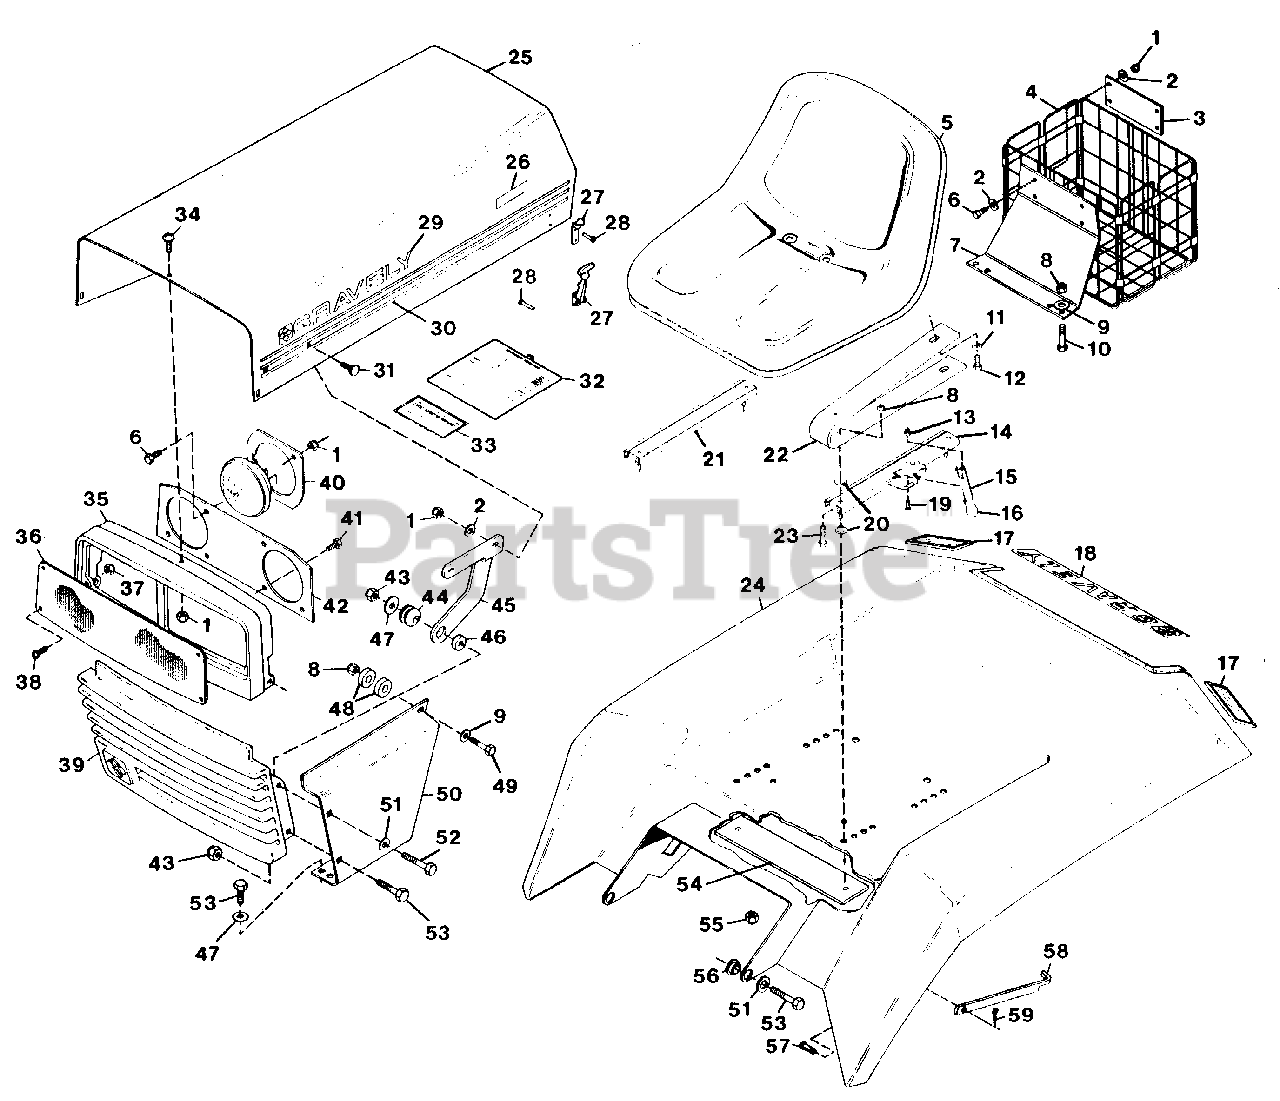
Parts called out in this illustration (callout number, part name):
1	NUT, LOCK 1/4-20
2	WASHER, FLAT .281X.625X.065
3	STRAP, BASKET
4	BASKET
5	SEAT, HIGH BACK
6	BOLT, HEX 1/4-20X1.00
7	BRACKET, BASKET
8	NUT, LOCK 5/16-18
9	WASHER, FLAT .344X.688X.065
10	BOLT, HEX 5/16-18X2.00
11	WASHER, LOCK 5/16 REG.
12	BOLT, HEX 5/16-18X.75
13	NUT, LOCK 10-24
14	ADJUSTER, SEAT W/LATCH
15	HANDLE, SEAT SLIDE
16	TIP, LEVER
17	REFLECTOR, RED SAFETY
18	DECAL, GRAVELY LOGO
19	SCREW, MACHINE 10-24X.625 PHD
20	BUSH., FLG. .375X1.16X.320 STL.
21	ADJUSTER, SEAT
22	SPRING, SEAT
23	BOLT, HEX 5/16-18X1.25
24	WELDMENT, SEAT PAN NOTCHED
25	HOOD, SILK SCREEN
26	DECAL, MODEL 24-G
27	LATCH, FLEXIBLE
28	RIVET, DOME HEAD
29	DECAL, GRAVELY LOGO
30	DECAL, SIDE STRIPE L.H. AND R.H.
31	BOLT, 1/4-20X.75 RD HD SQ NK
32	DECAL, MAINTENANCE
33	DECAL, ELECTRICAL SYSTEM WARNING
34	SCREW, MACHINE 1/4-20 PHD
35	BEZEL, HEADLIGHT
36	PANEL, HEADLIGHT LENSE
37	NUT, LOCK 10-24
38	SCREW, MACHINE 10-24X.75 PHD
39	CASTING, GRILLE
40	RING, HEADLIGHT RETAINER
41	SCREW, 1/4-20X.50 SELF-TAPPING
42	PANEL, HEADLIGHT REFLECTOR
43	NUT, LOCK 3/8-16
44	GROMMET
45	HINGE, HOOD L.H.
45	HINGE, HOOD R.H.
46	SPACER
47	WASHER, FLAT .438X1.000X.083
48	BUSH., ST. .391X1.00X.250 STL.
49	BOLT, HEX 5/16-18X1.75
50	PANEL, SIDE L.H.
50	PANEL, SIDE R.H.
51	WASHER, FLAT .406X.812X.065
52	BOLT, HEX 3/8-16X2.00
53	BOLT, HEX 3/8-16X1.00
54	BRACKET, SEAT
55	NUT, LOCK 5/16-18
56	BUSH., FLG. .406X.880X.270 BRZ.
57	PIN, CLEVIS .250X.406
58	STRAP, FENDER HOLD-UP
59	PIN, COTTER .06X.75
